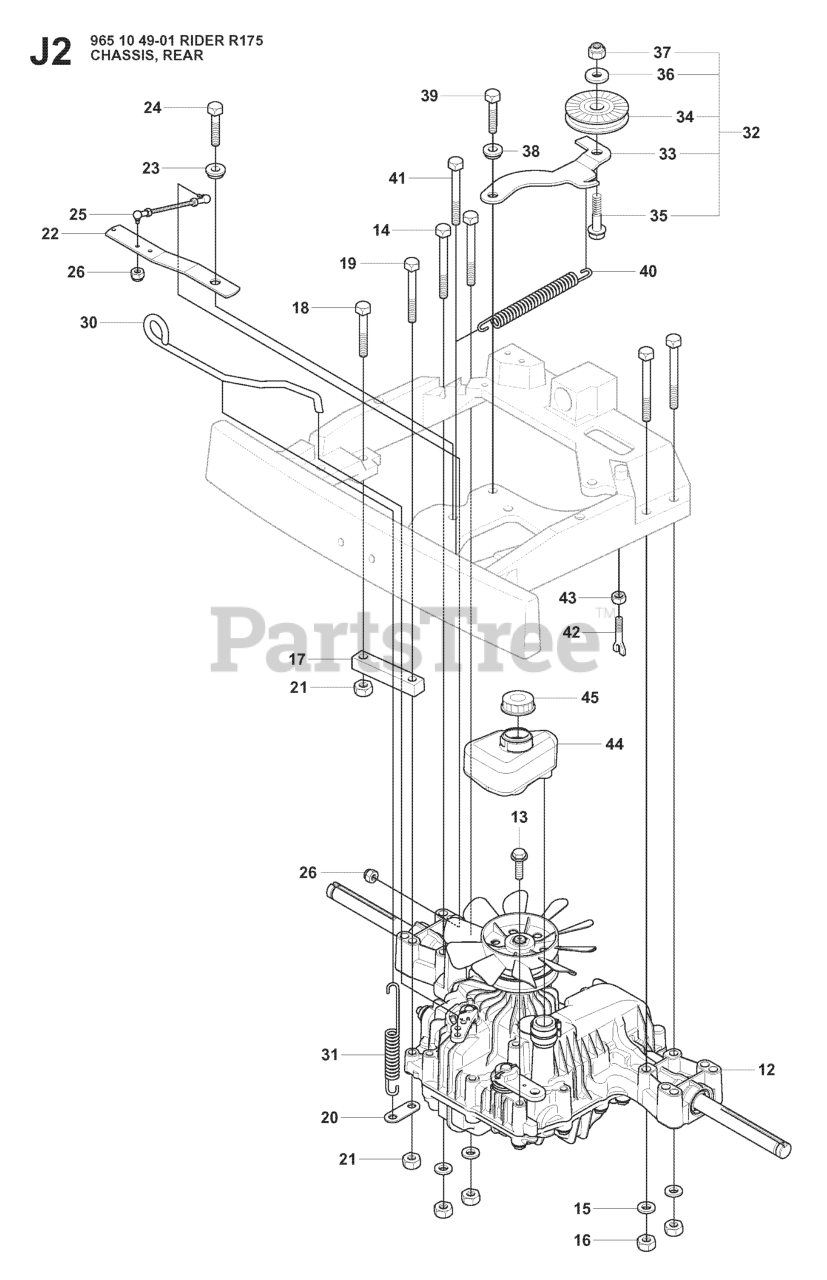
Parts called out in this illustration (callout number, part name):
2	Ball Bearing 6005-2rs
3	BALL BEARING 6010 2RS1
4	CIRCLIP SGH 47
5	RETAINING RING SGA 25
7	RETAINING RING SGA 25
47	REPL BY 725 25 00-71
48	COUNTERWEIGHT
